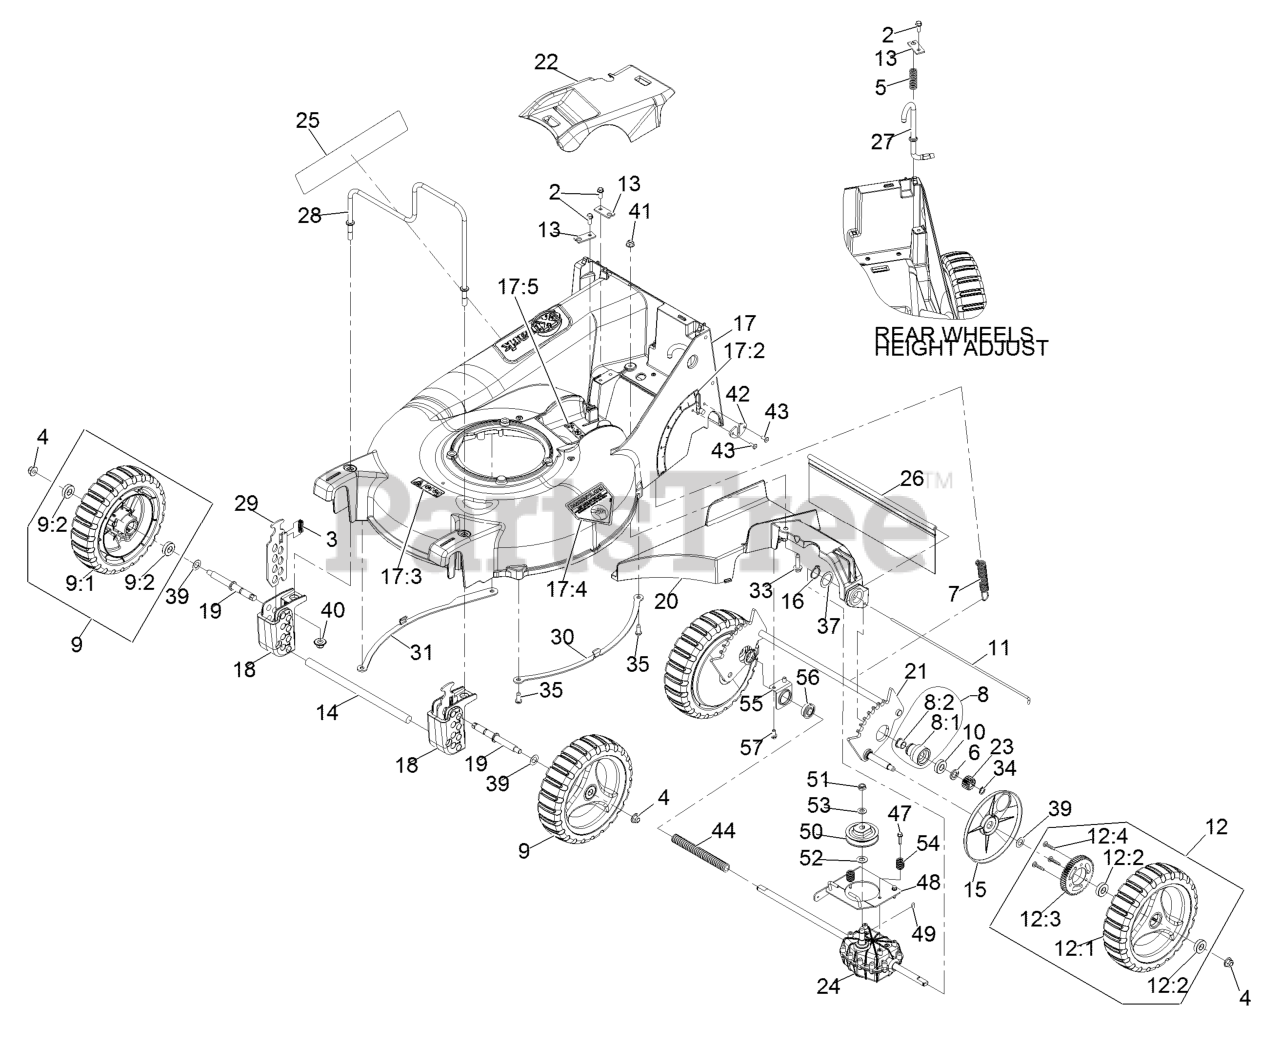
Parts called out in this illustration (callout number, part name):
2	SCREW-HWH
3	SPRING-COMPRESSION
4	NUT-HF, NI
5	SPRING-COMPRESSION
6	SPACER-BUSHING
7	SPRING-EXTENSION
8	HOUSING ASM
8:1	HOUSING-BEARING
8:2	BEARING-FLANGE
9:2	BEARING-BALL
10	BEARING-BALL
11	ROD,SHIELD
12:2	BEARING-BALL
12:4	SCREW-DRIVE
13	BRACKET,MOUNT
14	ROD,BUMPER
15	COVER,GEAR
16	RING-RETAINING
17	DECK W/DECALS
17:2	DECAL-HEIGHT OF CUT
17:3	DECAL-WARNING, BLADE
17:4	DECAL-DANGER
17:5	DECAL-DANGER
18	BLOCK,FRONT QUADRANT
19	AXLE-WHEEL
20	BRACKET-TRANSMISSION AND
21	WLD,REAR AXLE P21
22	COVER,BELT
24	TRANSMISSION-HD, 4.5/1
25	DECAL-COMM 21 X-SERIES
26	SHIELD-TRAILING P21
27	ROD-HEIGHT ADJ P21
28	GUARD,ENGINE
29	PLATE, FRONT HEIGHT
33	SCREW-HWHTF
34	RING-RETAINING
35	SCREW-BHTF
39	WASHER-PLAIN
40	Nut-Nyloc 3/8-16 Flg
41	NUT-HF, NI
42	PLATE,WEAR
43	RIVET-BLIND
44	COVER-SHAFT-DRIVE
47	SCREW-SPECIAL
48	TRANSMISSION PLATE ASM
49	KEY-WOODRUFF
51	NUT-HEX
52	WASHER-THRUST
53	WASHER-FLAT
54	SPRING,COMPRESSION
56	BEARING-BALL
57	SCREW-HWH
